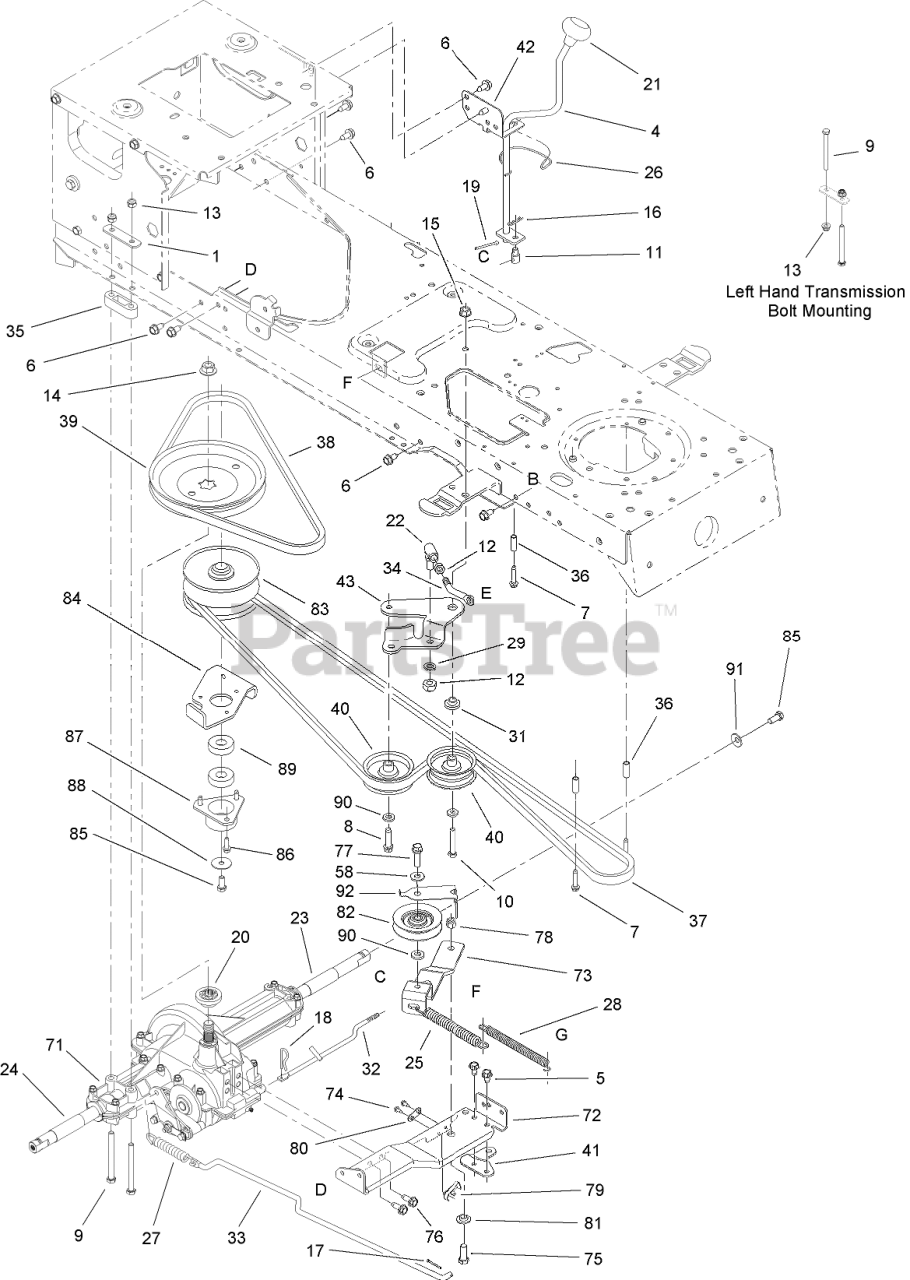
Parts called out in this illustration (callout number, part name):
1	BRACKET-MOUNTING, TRANSMISSION
4	SHIFT LEVER ASM
5	SCREW-TAP
6	SCREW-HH, TAP
7	SCREW-HH
8	SCREW-TAP
9	SCREW-HH
10	SCREW-HH
11	FERRULE-ADJUSTABLE
12	NUT-HEX
13	NUT-LOCK, FLANGE
14	NUT-FLANGE
15	NUT-LOCK, FLANGE
16	PIN-COTTER
17	PIN-COTTER
18	PIN-HAIR
19	PIN-COTTER
20	HUB-PULLEY
21	KNOB-SHIFT
22	BALL JOINT ASM
23	SLEEVE
24	SLEEVE
25	SPRING-EXTENSION
26	CLIP-SPRING, SHIFTER
27	SPRING-EXTENSION
28	SPRING-EXTENSION
29	WASHER-LOCK
31	SPACER-SHOULDER
32	ROD-SHIFT
33	ROD-BRAKE
34	ROD-ADJUSTMENT, IDLER
35	SPACER-TRANSAXLE
36	SPACER
37	BELT-DRIVE, VARIABLE SPEED
38	BELT-DRIVE, TRANSMISSION
39	PULLEY-V (W/HUB)
40	PULLEY-IDLER, FLAT
41	BRACKET-SHIFT
42	BRACKET-SHIFT
43	BRACKET-IDLER, CENTER DOUBLE
58	Washer-Flat
71	SINGLE SPEED TRANSMISSION ASM
72	BRACKET-TORQUE
73	IDLER BRACKET KIT
74	SCREW-HWHTF
75	SCREW-HH
76	SCREW-HWH
77	SCREW-TAP
78	NUT-LOCK, HEX
79	SWITCH-SPRING, SHORT
80	PLATE-INSULATOR
81	SPACER-SHOULDER
82	PULLEY-IDLER, V-TYPE
83	VARIABLE SPEED PULLEY ASM
84	BRACKET-PULLEY
85	SCREW-HH
86	SCREW-TAP
87	CUP-BEARING
88	WASHER-FLAT
89	BEARING-BALL
90	WASHER-FLAT
91	WASHER-BELL
92	GUIDE-BELT, TRACTION
